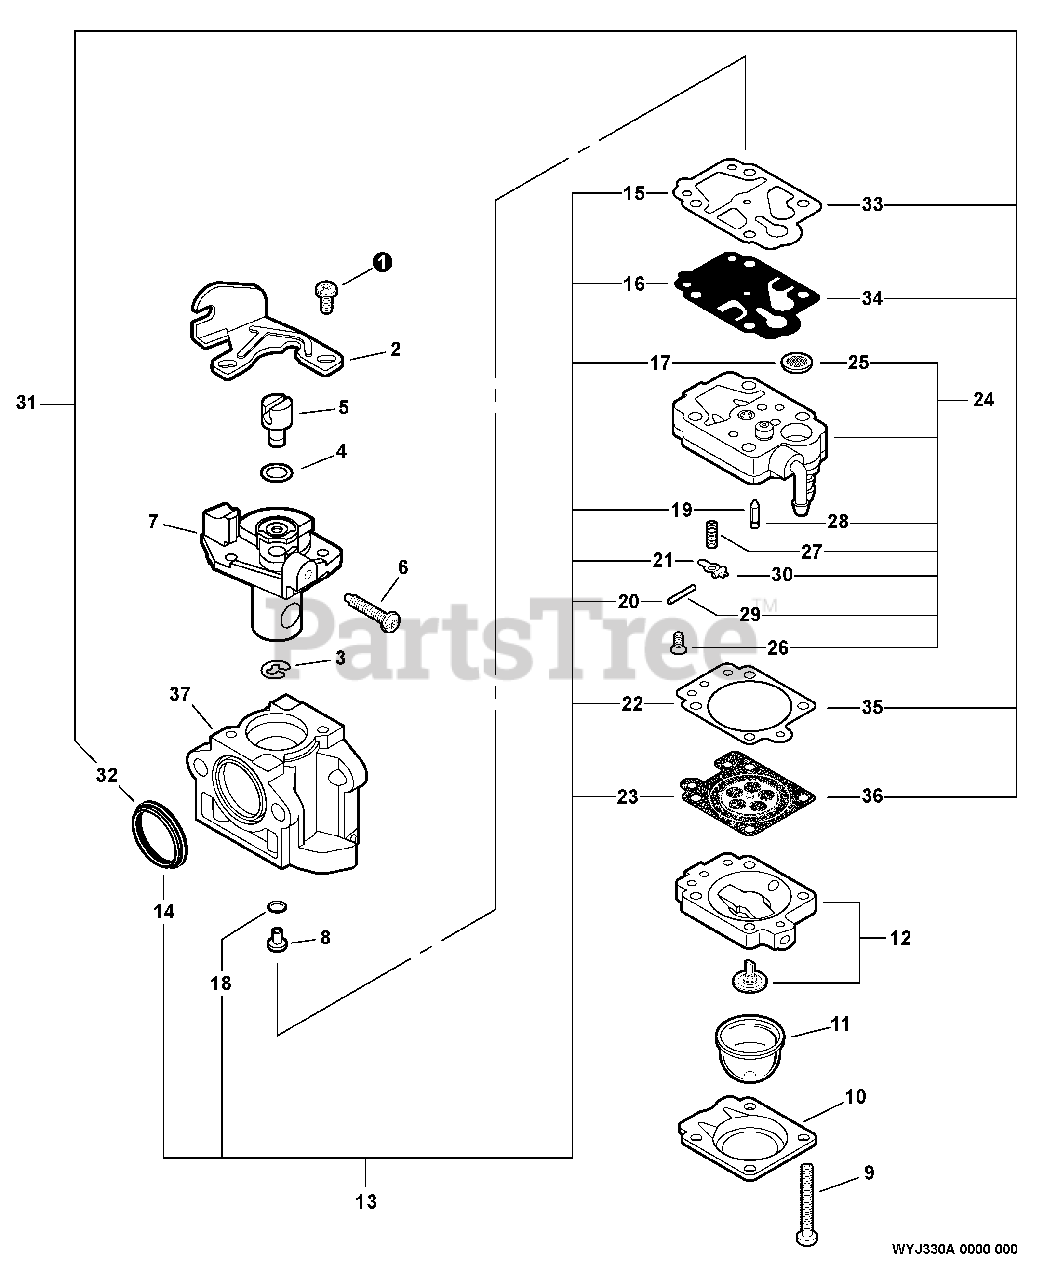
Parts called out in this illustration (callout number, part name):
2	BRACKET, CABLE
3	RING, RETAINING
6	SCREW, IDLE ADJUST
7	THROTTLE VALVE ASSY
8	JET, MAIN
9	SCREW, PUMP COVER
10	RETAINER, PURGE BULB
11	BULB, PURGE
12	PURGE BASE ASSY
13	REPAIR KIT
14	SEAL
15	GASKET, PUMP
16	DIAPHRAGM, PUMP
17	STRAINER
18	O-RING
19	VALVE, INLET NEEDLE
20	PIN, METERING LEVER
21	LEVER, METERING
22	GASKET, METERING
23	DIAPHRAGM, METERING
24	PUMP BODY ASSY
25	STRAINER
26	SCREW, METERING LEVER PIN
27	SPRING, METERING LEVER
28	VALVE, INLET NEEDLE
29	PIN, METERING LEVER
30	LEVER, METERING
31	DIAPHRAGM/GASKET KIT
32	SEAL
33	GASKET, PUMP
34	DIAPHRAGM, PUMP
35	GASKET, METERING
36	DIAPHRAGM, METERING
37	BODY, CARBURETOR
